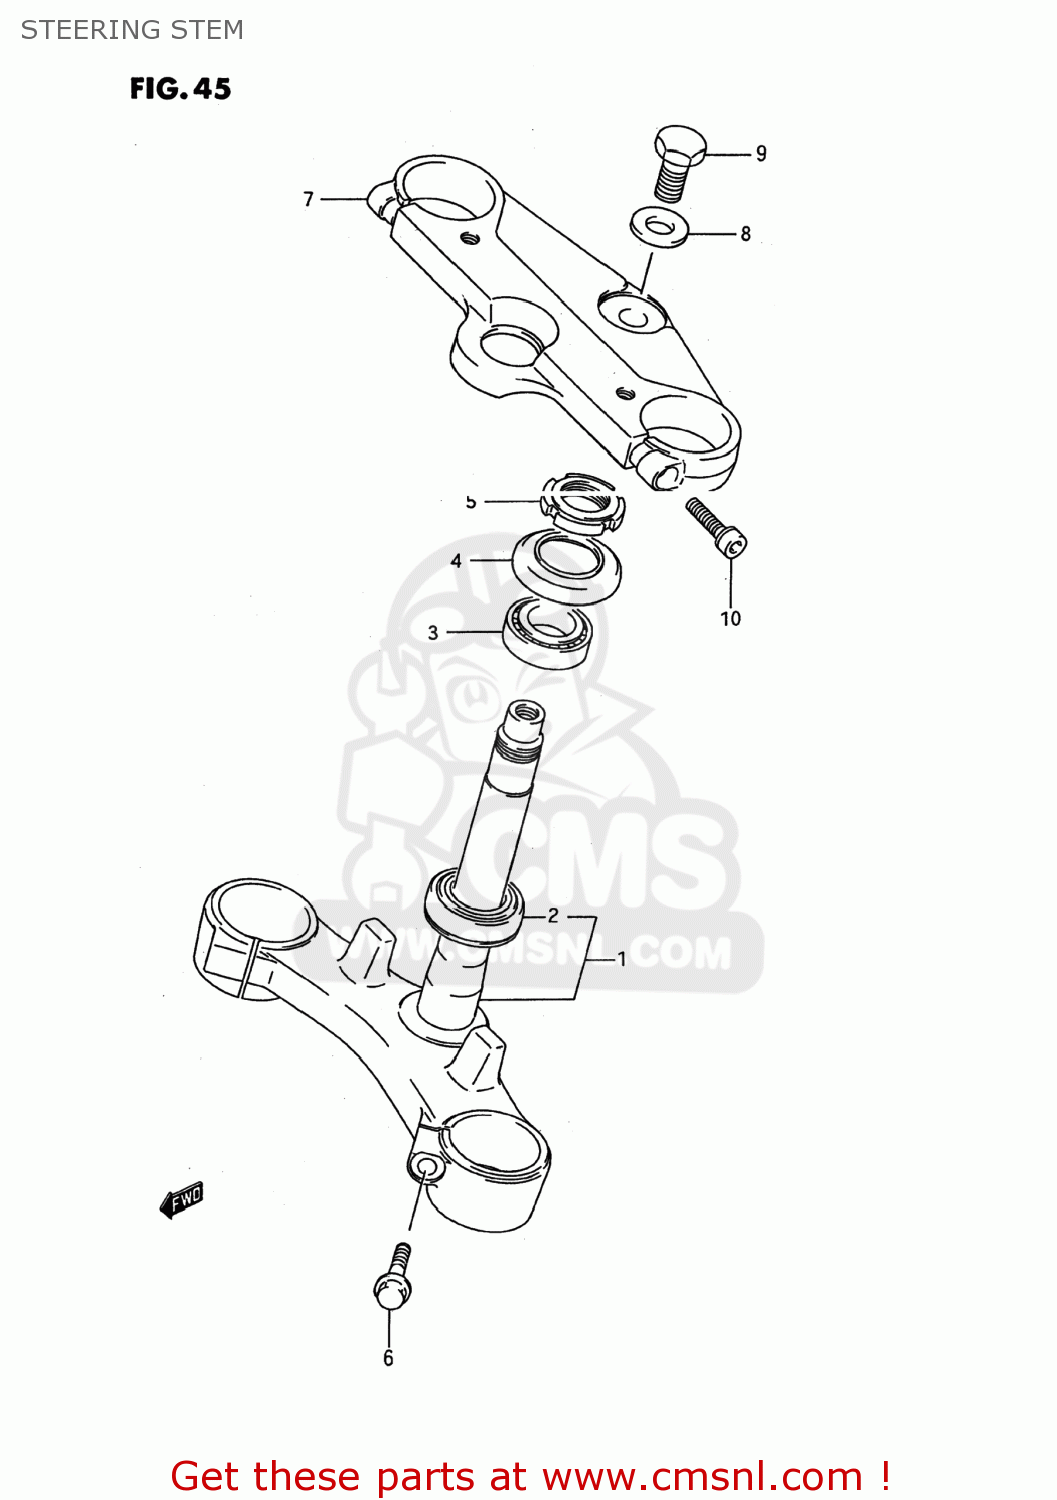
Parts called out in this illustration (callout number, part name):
1	STEM,STEERING
2	BEARING(30X55X17)
3	TAPER,ROLLER BEARING
4	SEAL,STEERING UPR DUST
5	NUT,STEERING STEM(25X44X10)
6	BOLT
7	BRACKET,UPPER
8	WASHER,STEERING STEM
9	BOLT,STEERING STEM HEAD
10	BOLT
